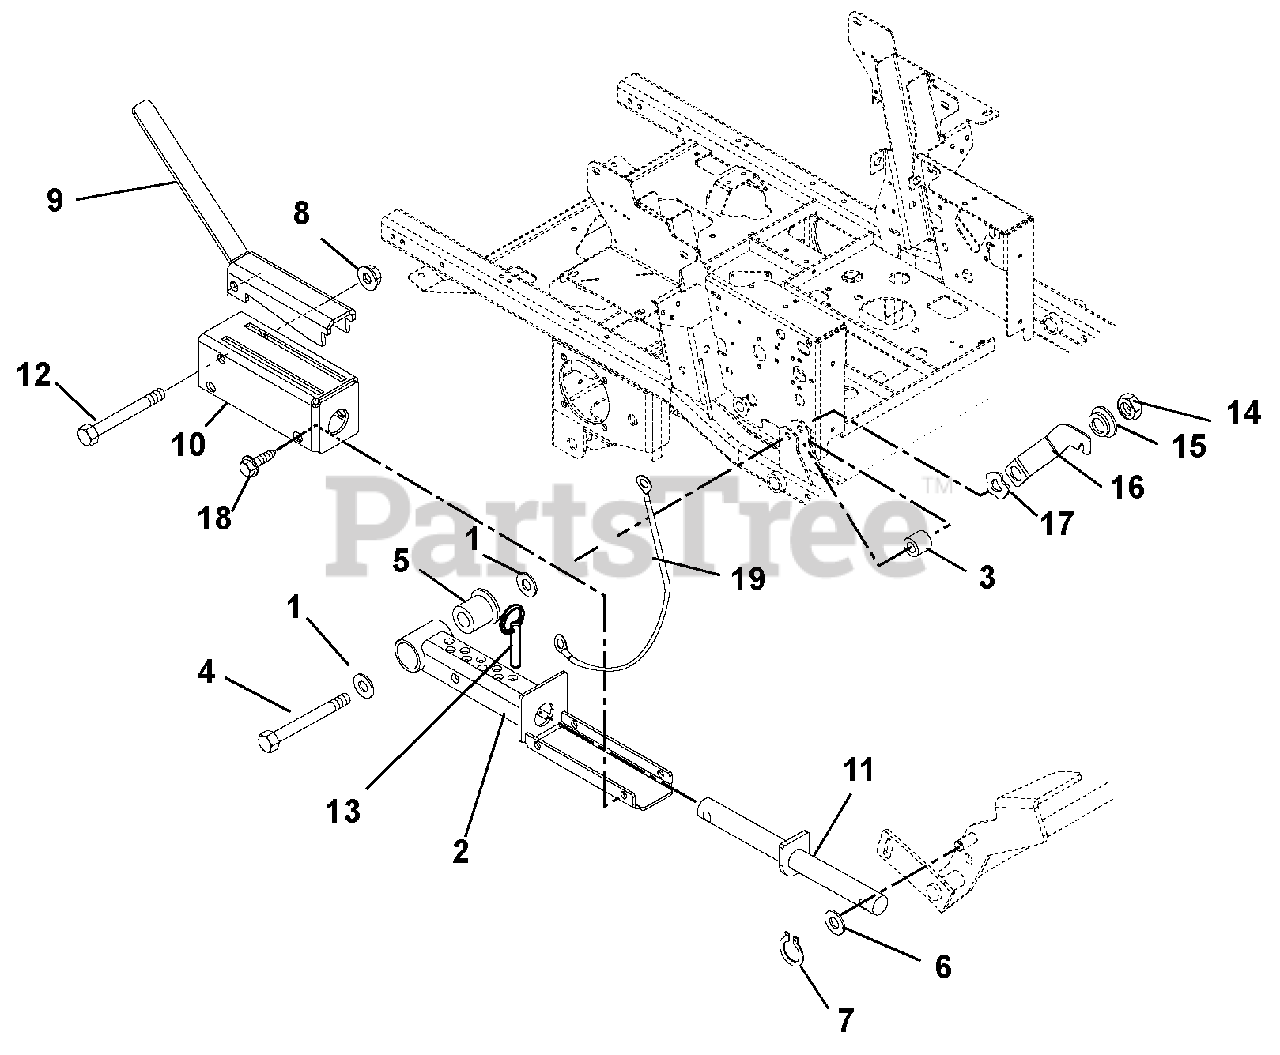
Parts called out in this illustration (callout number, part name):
1	Washer, Flat Steel .531 x 1.250 x .10
2	Weldment, Mechanical Lift
3	Bushing .516 x 1.00 x 1.05
4	Bolt, Hex .50-13 x 5.00 Grade 5
5	Bearing, Pedestal Powdered Metal
6	Washer, Flat Steel .656 x 1.310 x .095
7	Ring, Retaining External .625 x .050
8	Nut, Locking Top Flange .38-16
9	Lock-Up, Mechanical Lift
10	Weldment, Mechanical Lift Cover
11	Weldment, Mechanical Lift Shaft
12	Bolt, Hex .38-16 x 3.25 Grade 5
13	Pin, Spring Ball .375 O.D. x 1.50
14	Nut, Locking Top Flange .50-13
15	Bushing, Flange .515 x .75 x .275 x 1.12
16	Latch, Footboard
17	Washer, Wave .076 x 1.12 x .08
18	Screw, Tapping .38-16 x .50
19	Cable, 12.0 Lanyard, Nylon
